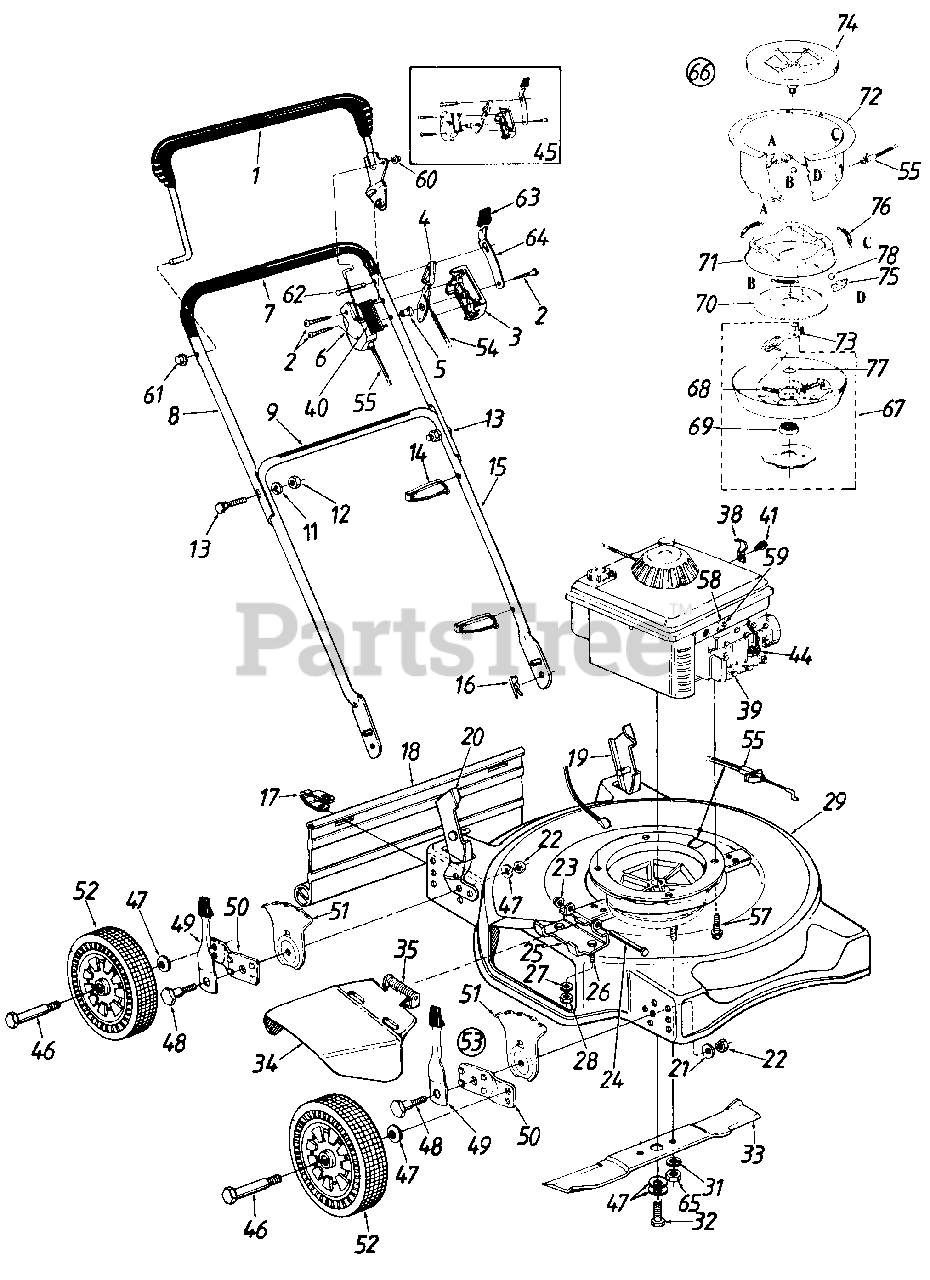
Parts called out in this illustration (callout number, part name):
1	Control Handle Ass'y.
2	Truss Mach. Scr. #12 x 1.5" Lg.
3	Control Panel Half
4	Throttle Control Lever
5	Control Disc Pin
6	Clutch Panel Half
8	Upper Handle
9	Instruction Label-Handle
11	L-Wash. 5/16" I.D.
12	Hex Nut 5/16-18 Thd.
13	Curved Carriage Bolt 5/16-18 x 1.38" Lg.
14	Cable Tie
15	Lower Handle
16	Hairpin Cotter
17	Hinge Clip
18	Rear Flap
19	Handle Bracket Ass'y.-L.H.
20	Handle Bracket Ass'y.-R.H.
21	Bell-Wash. .39" I.D. x 1.38"
22	Hex Nut 3/8-16 Thd.
23	Push Cap 1/4" Rod
24	Pivot Pin
25	Adapter Plate
26	Hex Bolt 1/4-20 x .50" Lg.
27	L-Wash. 1/4" I.D.
28	Hex Nut 1/4-20 Thd.
29	20" Deck Ass'y.
32	Hex Cent. L-Bolt 3/8-24 x 2.0" Lg.
33	20" Blade
34	Chute Deflector Ass'y.
35	Torsion Spring
38	Cable Clamp
39	Engine
40	Control Label-Throttle
41	Hex B-Tap Scr. #10 x .38"
44	Spark Plug Boot
45	Kit-Control Housing Comp.
46	Axle Bolt
47	Bell-Wash. .400" I.D. x .88"
48	Shld. Bolt .50" Dia. x .357"
49	Spring Lever Ass'y. w/Knob
50	Pivot Bar
51	Height Adj. Plate
52	Wheel Ass'y. Comp.
53	Height Adj. Ass'y. Comp.-R.H.
54	Throttle Cable-51"
55	Control Cable
57	Hex L-Wash. Hd. Scr. 3/8-16 x 1.0" Lg.
58	Cable Clamp
59	Hex B-Tap Scr. #10 x .62" Lg.
60	Push Cap
61	Cap Speed Nut
62	Lock Pin
63	Spring Lever Knob
64	Lockout Spring
65	Hex Nut 5/16-24 Thd. (Grade. 8)
66	Blade Brake Clutch Ass'y. Comp.
67	Clutch Blade Housing Ass'y.
68	Comp. Spring .35" O.D. x 2.0" Lg.
69	Ball Brg. .669" I.D. x 1.574" O.D.
70	Clutching Cone
71	Brake Cup Cone
72	Clutch Housing
73	Hex Wash. TT-Tap Cl.-Scr. 1/4-20 x .75" Lg.
74	Fan Adapter
75	Ball Block
76	Ext. Spring .35" O.D. x 1.75" Lg.
77	Fl-Wash. .69" I.D. x 1.060"
78	Steel Ball .5" Dia.
